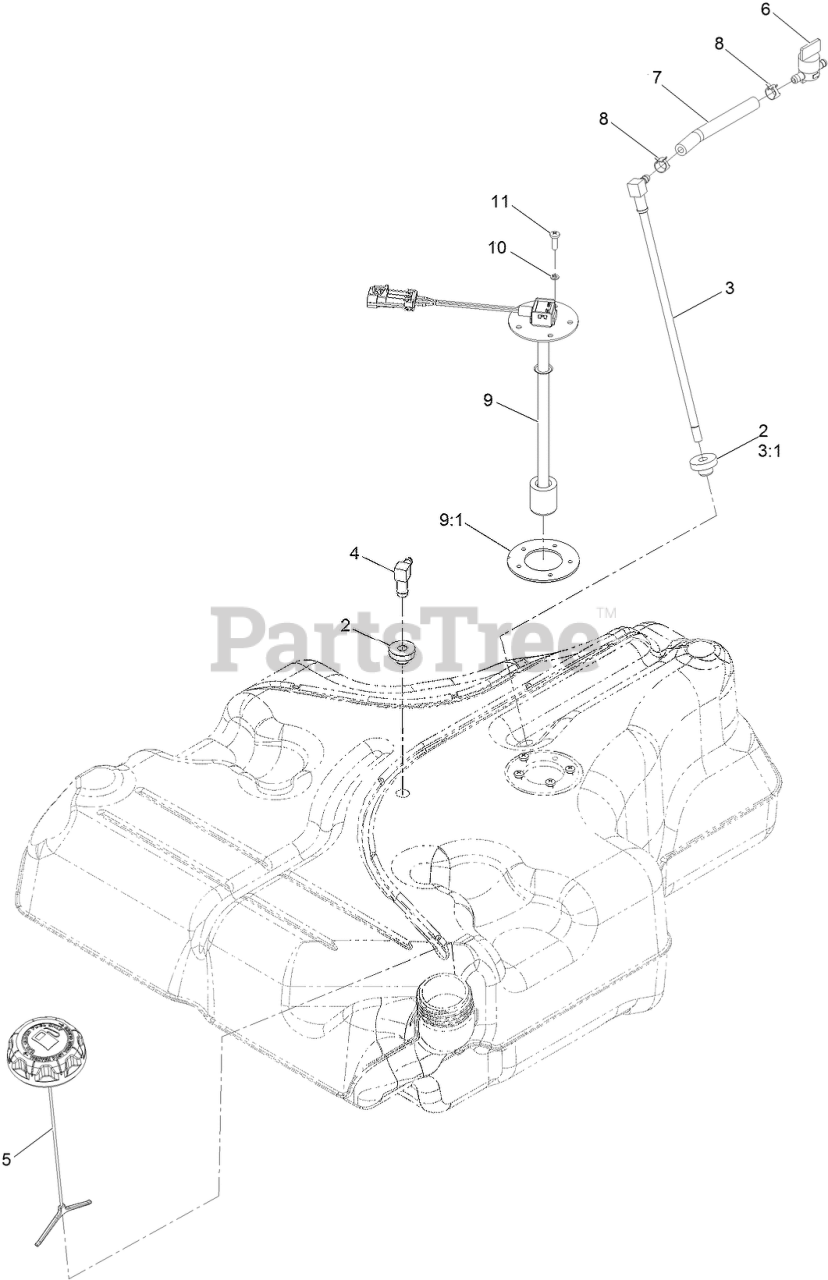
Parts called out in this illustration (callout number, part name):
2	BUSHING
3	FUEL LINE KIT (WITH GROMMET)
3:1	BUSHING
4	FITTING-90 ELBOW
5	CAP-FUEL, RATCHETING
6	VALVE-FUEL
7	HOSE-FUEL
8	CLAMP-HOSE
9	SENDER-LEVEL, FUEL (W/GAS
9:1	Gasket-Sender
10	WASHER-LOCK
11	SCREW-PPH
